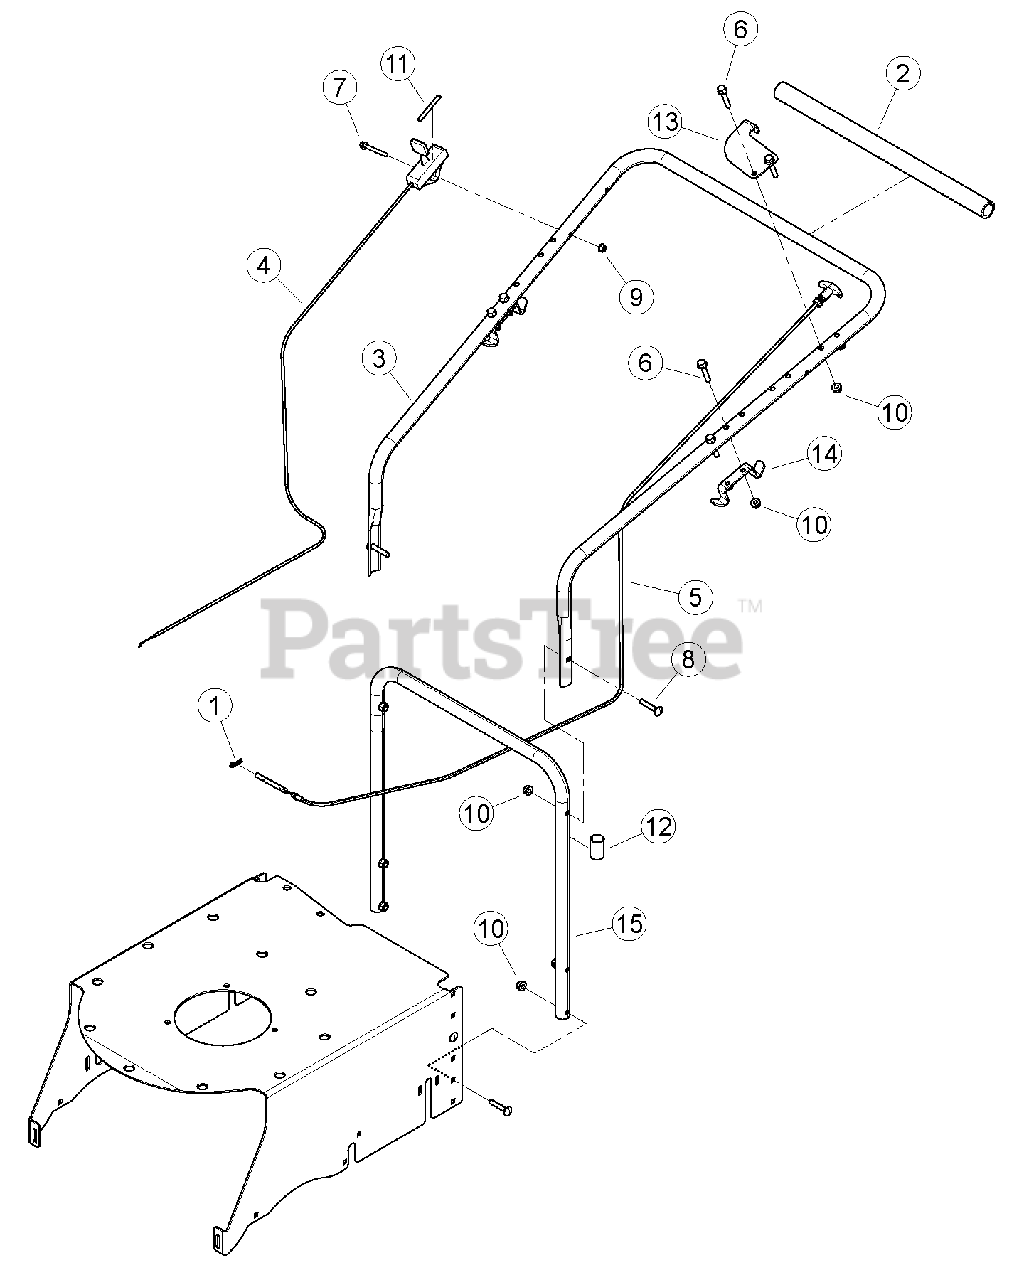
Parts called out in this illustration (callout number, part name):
1	CLIP, HAIRPIN ZP
2	PAD, FOAM HANDLEBAR
3	HANDLEBAR, BEARVAC UPPER
4	CONTROL, THROTTLE
5	CONTROL, HEIGHT ADJUSTMENT
6	BOLT, 5/16 X 1-3/4 FLANGE NC
7	BOLT, 1/4 X 2 FLANGE NC
8	BOLT, 5/16 X 1-3/4 GR5 CRG ZP
9	NUT, 1/4-20 NYLOCK-FLANGE
10	NUT, 5/16-18 NYLOCK-FLANGE
11	DECAL, THROTTLE
12	CAP, 7/8" PLASTIC
13	BRACKET, BEARVAC CABLE MOUNT
14	BRACKET, BAG HANGER
15	HANDLEBAR, LOWER BEARVAC
